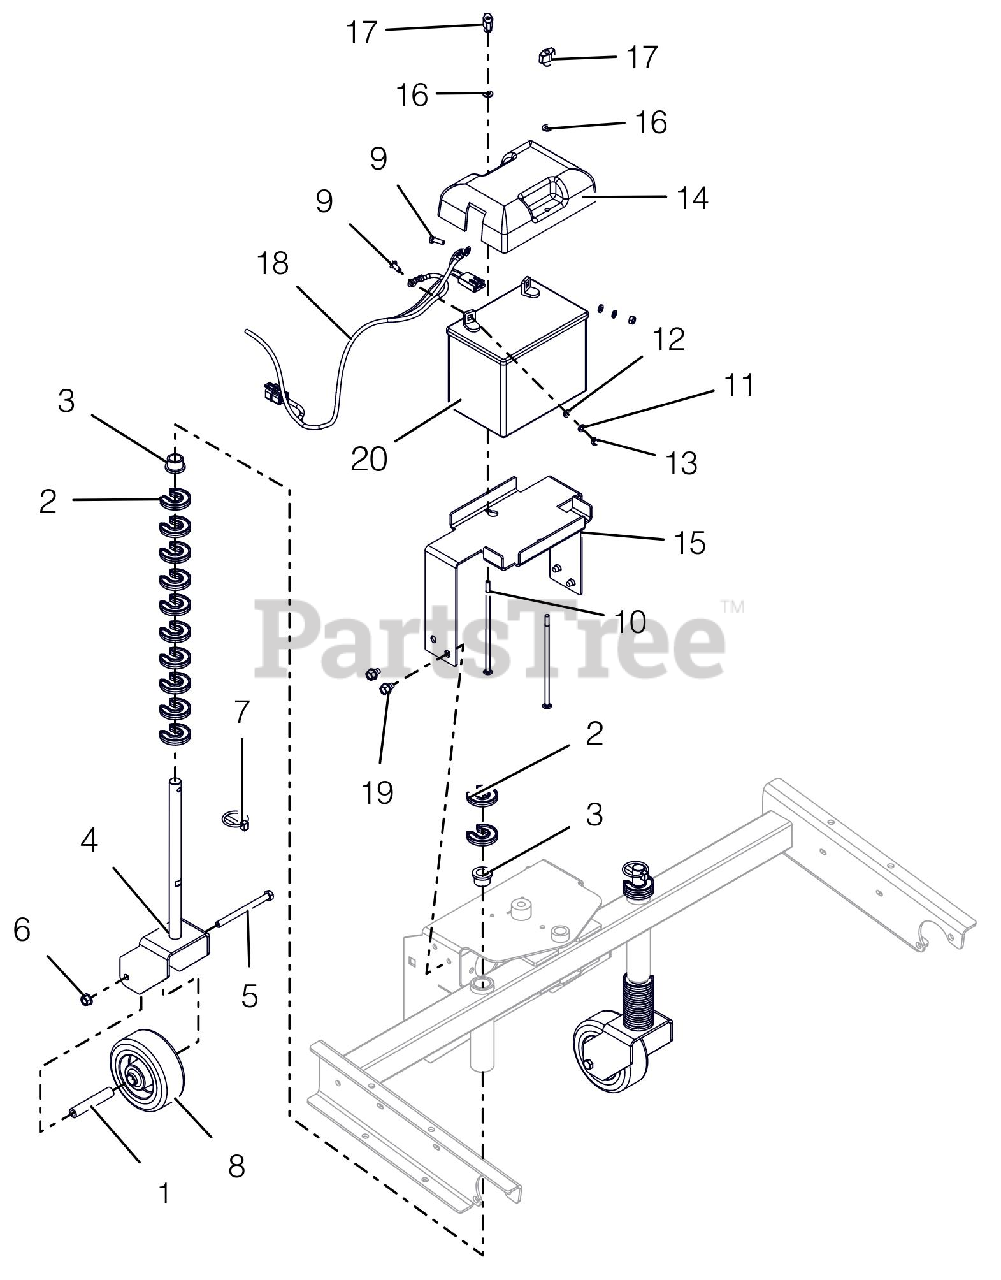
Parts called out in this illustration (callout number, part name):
1	SPACER, CASTER WHEEL
2	CLIP-HOC FIXED
3	BUSHING, FLANGE .75X.75X1.0
4	FORK, CASTER
5	@BLT-HEX .38-16X4.50 GR5 YWZC
6	@NUT-LK-TOP-FLG .38-16 YWZC
7	PIN, 1/4X1-9/16 LYNCH
8	WHEEL, CASTER - 5"OD
9	@BLT-HEX .25-20X.75 GR5 YWZC
10	@BLT-RDHDSQNK .25-20X7.00 G2YZ
11	@WSHR-LK .25X.062 REG YWZC
12	WSHR-FL-STL .265X.50X.087YWZC
13	@NUT-HEX .25-20 YWZC
14	COVER, BATTERY
15	TRAY, BATTERY - POWER BRUSH
16	@WSHR-FL-STL.281X.62X.065 YWZC
17	KNOB, WING - .25-20 UNC
18	HARNESS,ELEC - ENGINE 12V
19	@SCR-TAP .38-16X.50 HWH TR YWZ
20	BATTERY, 300 CCA 10U1L
